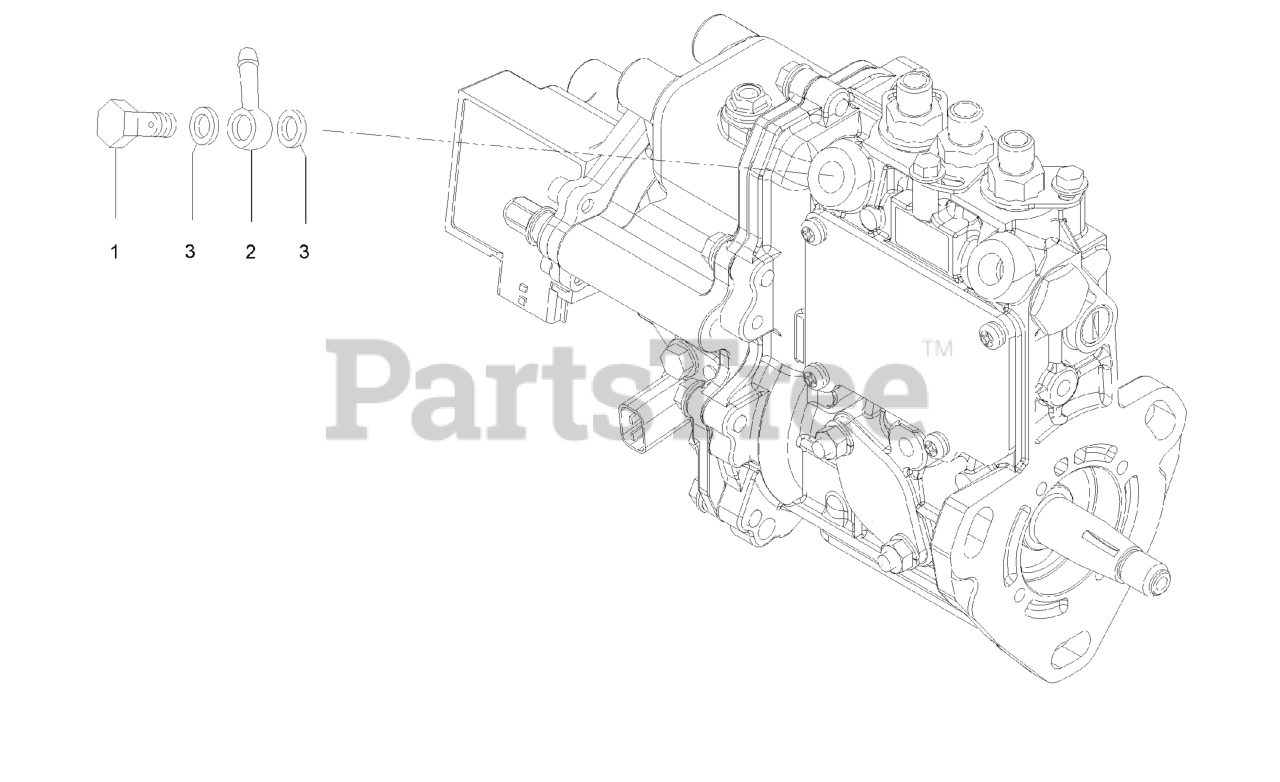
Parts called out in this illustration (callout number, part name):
1	BOLT-PIPE JOINT
2	JOINT-PIPE
3	WASHER-SEAL
